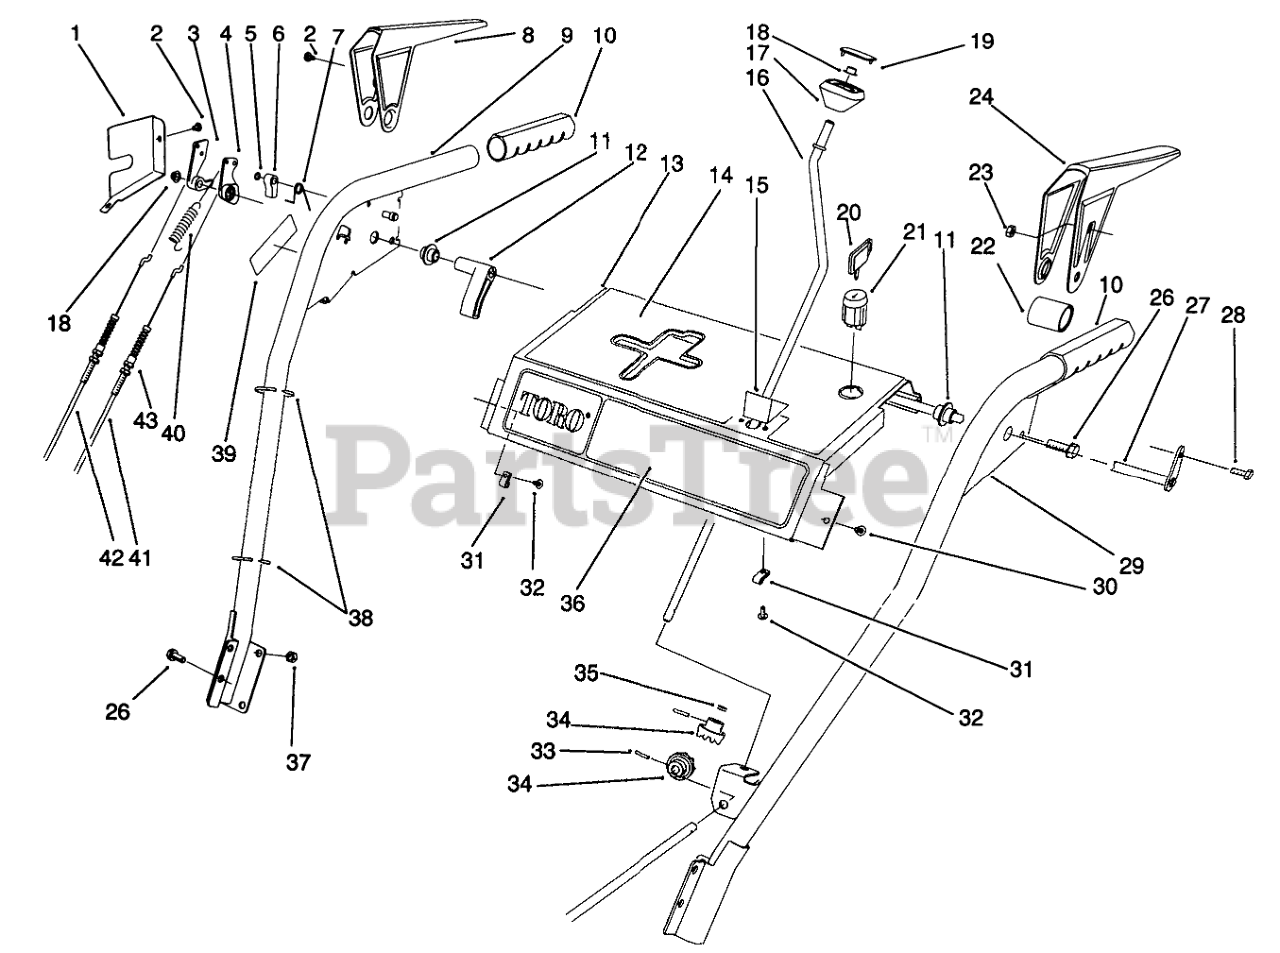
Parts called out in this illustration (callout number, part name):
1	Cover Lever Lock
2	SCREW-HH
3	TANG-LOCKING
4	CAM-RELEASE
5	E-RING-RETAINER
6	LATCH-LOCKING
7	SPRING-TORSION
8	Lever-Impeller
9	Handle-RH
10	GRIP-HANDLE
11	BUSHING-LEVER
12	LEVER-TRIP
13	Panel-Control
14	Decal-Panel, Top
15	PLATE-GUIDE
16	CRANK-ROD, CHUTE
17	KNOB-CONTROL, CHUTE
18	RETAINER-PUSH ON
19	COVER-KNOB
20	KEY-IGNITION
21	SWITCH
22	SPACER-LEVER, TRACTION
23	NUT-LOCK, NI
24	Lever-Traction
26	SCREW-HHF
27	CROSS ROD ASM
28	SCREW-HWH
29	Handle-LH
30	SCREW-HWHTF
31	R CLAMP
32	SCREW-PPH
33	PIN-SPRING
34	GEAR-UNIVERSAL
35	WASHER-RUBBER
36	DECAL-FRONT PANEL
37	NUT-LOCK, NI
38	TIE-CABLE
39	DECAL-WARNING
40	Spring-Extension
41	CABLE-TRACTION
42	CABLE-IMPELLER
43	NUT-LOCK, NI
